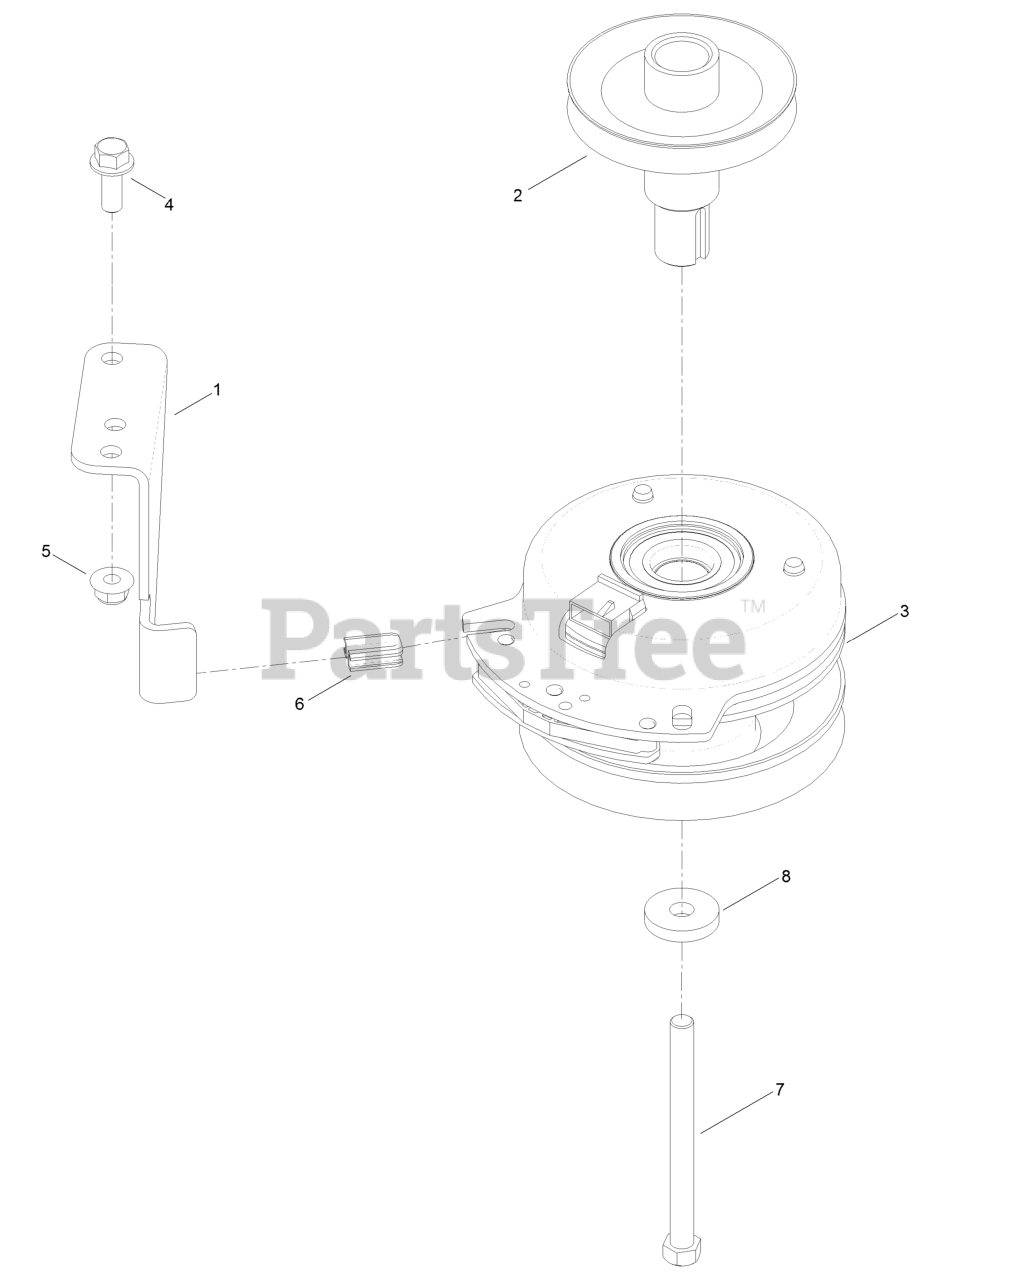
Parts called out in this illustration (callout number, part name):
1	STOP-CLUTCH
2	PULLEY-ENGINE
3	CLUTCH-PTO
4	SCREW-HHF 3/8-16 X 1
5	NUT-HF, NI
6	ISOLATOR-CLUTCH
7	SCREW-HH
8	WASHER
